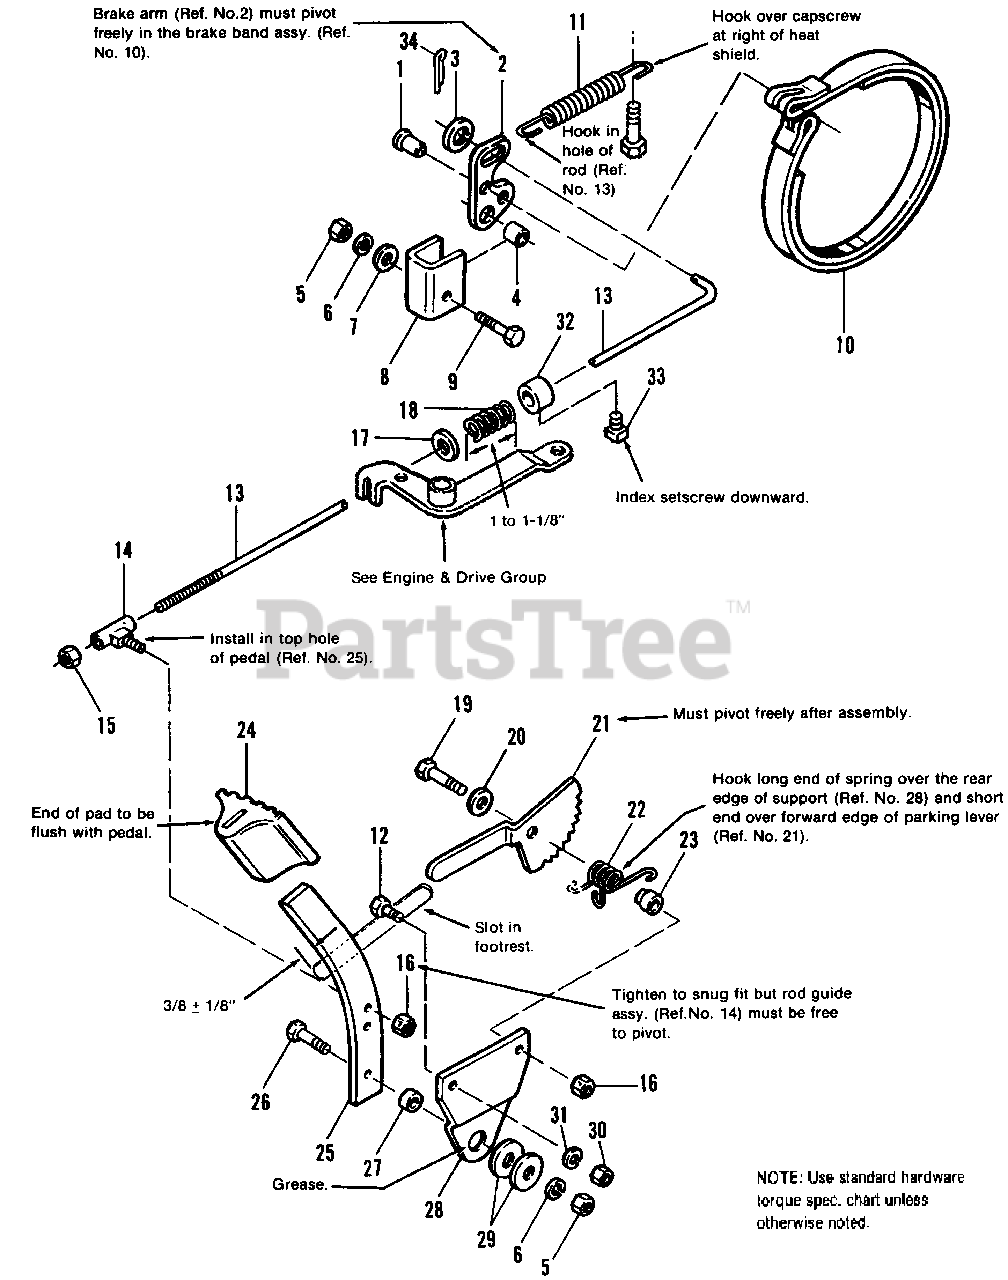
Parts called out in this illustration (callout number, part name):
2	ARM, Brake
3	WASHER, Plain
5	NUT, Hex, 3/8-16
6	LOCKWASHER, 3/8
7	WASHER, Plain, 5/16
8	BRACKET, Brake
9	CAPSCREW, Hex Hd., 3/8-16 x 1-3/4
10	BRAKE BAND ASSY.
12	CAPSCREW, Hex Hd., 5/16-18 x 3/4
13	ROD, Brake
14	ROD GUIDE ASSY.
15	LOCKNUT, Esna, 5/16-18
16	LOCKNUT, Hex, 5/16-18
17	WASHER, Plain, 13/32 x 1
19	CAPSCREW, Hex Hd., 5/16-18 x 1-1/2
20	WASHER, Plain, 11/32
21	LEVER, Parking Brake
22	SPRING Torsion
25	PEDAL, Brake
26	CAPSCREW, Hex, 3/8-16 x 1-1/4
28	SUPPORT, Pedal
30	NUT, Hex, 5/16-18
31	LOCKWASHER, 5/16
32	COLLAR, Set
33	SCREW, Set, Sq. Hd., Cup Pt., 1/4-20 x 3/8
34	PIN, Cotter
